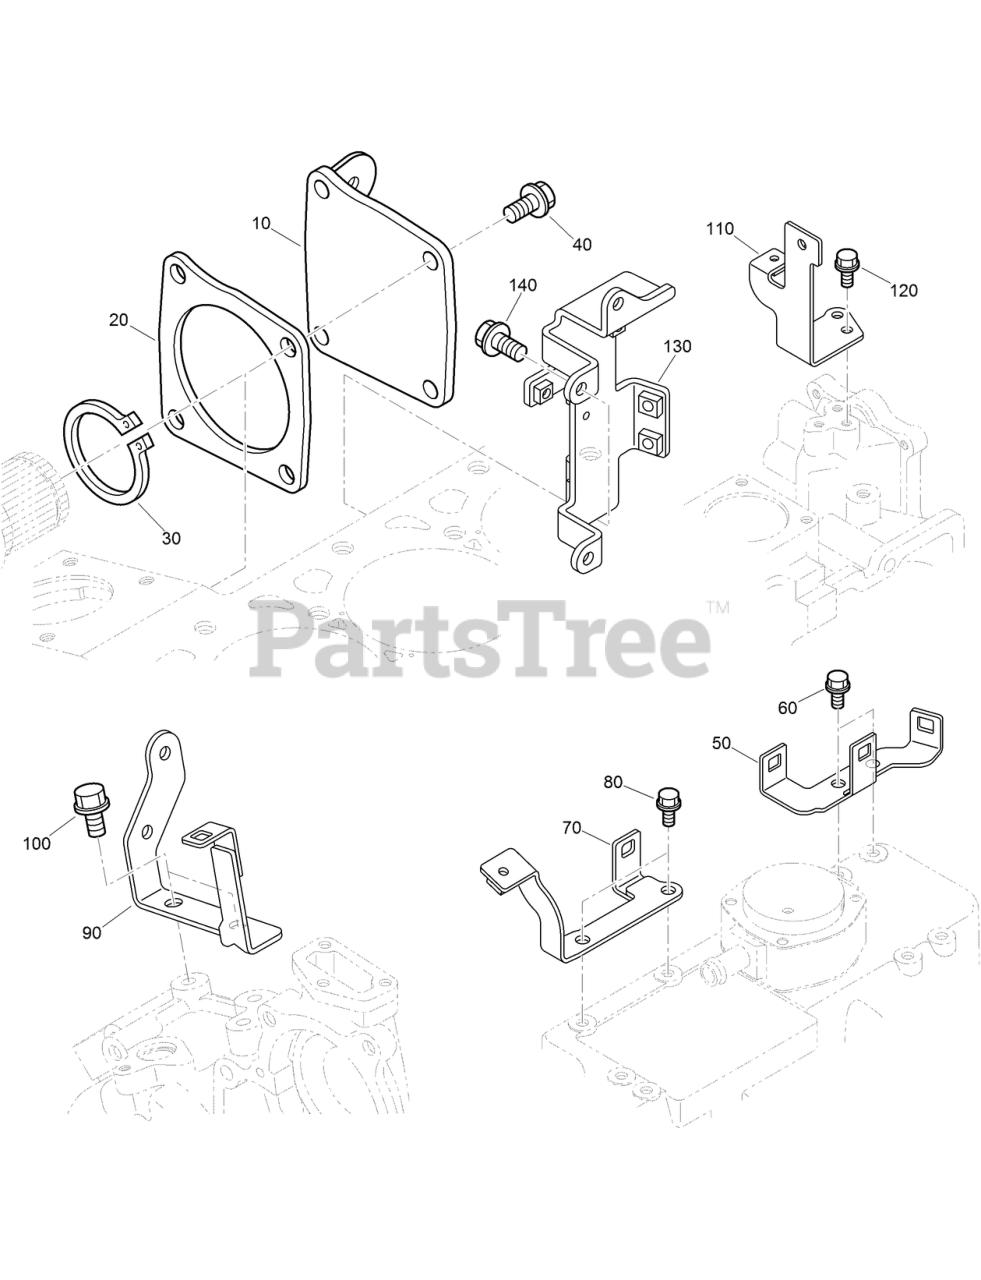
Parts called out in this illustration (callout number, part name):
10	COVER-CAMSHAFT, FUEL
20	GASKET
30	CIRCLIP-EXTERNAL
40	BOLT-FLANGE
50	BRACKET-HARNESS
60	BOLT-FLANGE
70	BRACKET (WH 2)
80	BOLT-FLANGE
90	BRACKET (WH 3)
100	BOLT-FLANGE
110	BRACKET (WH 4)
120	BOLT-FLANGE
130	BRACKET-CONNECTOR
140	BOLT-FLANGE
